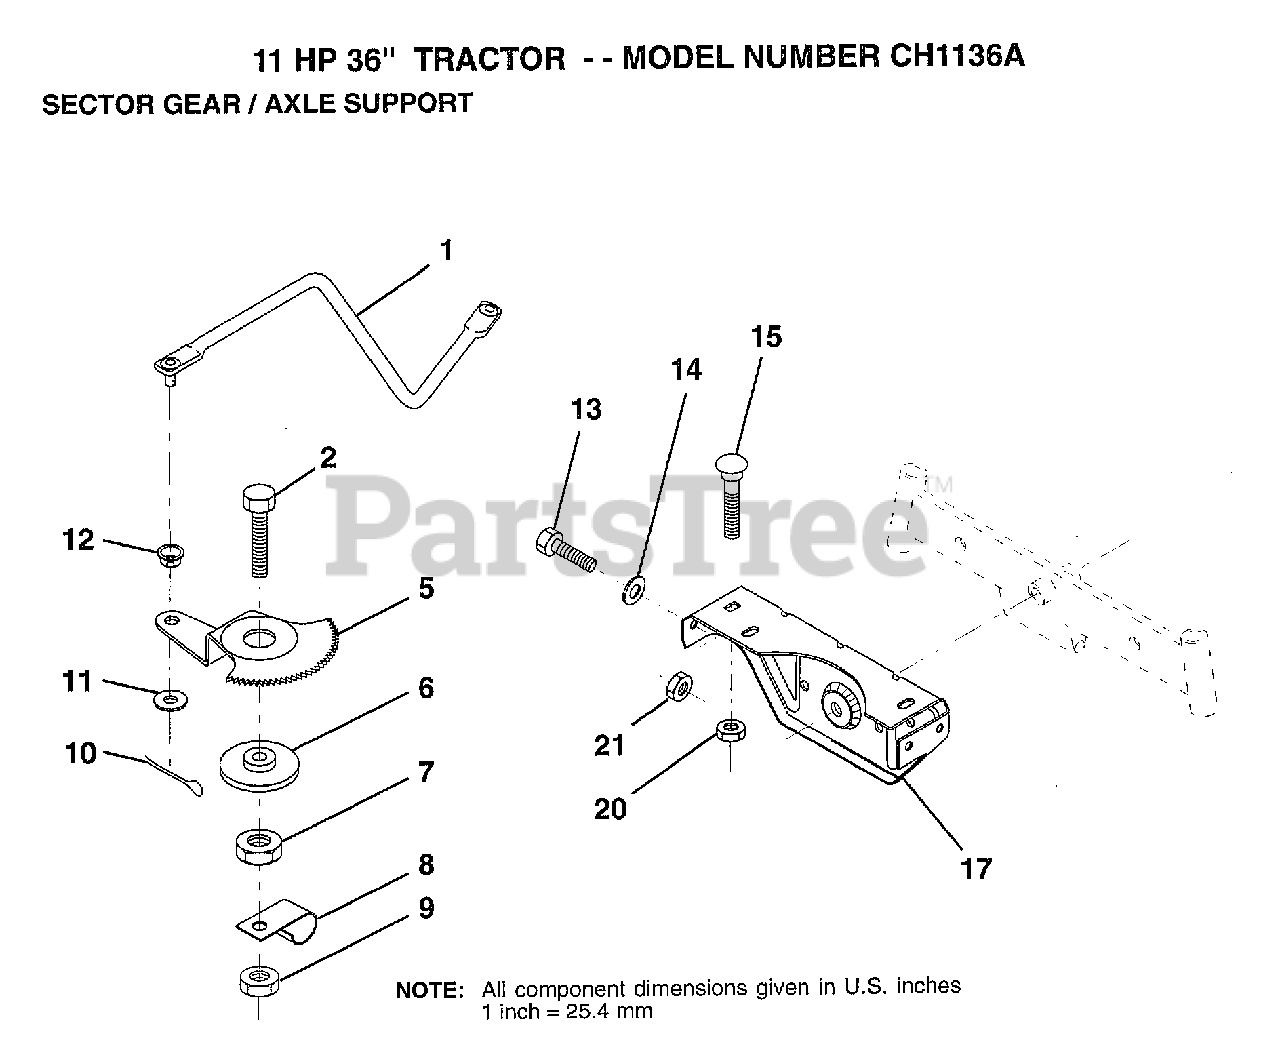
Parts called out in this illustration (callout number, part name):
1	DRAG LINK
2	"BOLT,HEX"
5	GEAR SECTOR
6	BUSHING
7	NUT
8	CLIP INSULATOR
9	NUT LTV
10	COTTER PIN
11	WASHER
12	BUSHING.DRAGLINK
13	BOLT
14	WASHER
15	BOLT
17	SUPT AXLE FRONT
20	NUT
21	NUT
